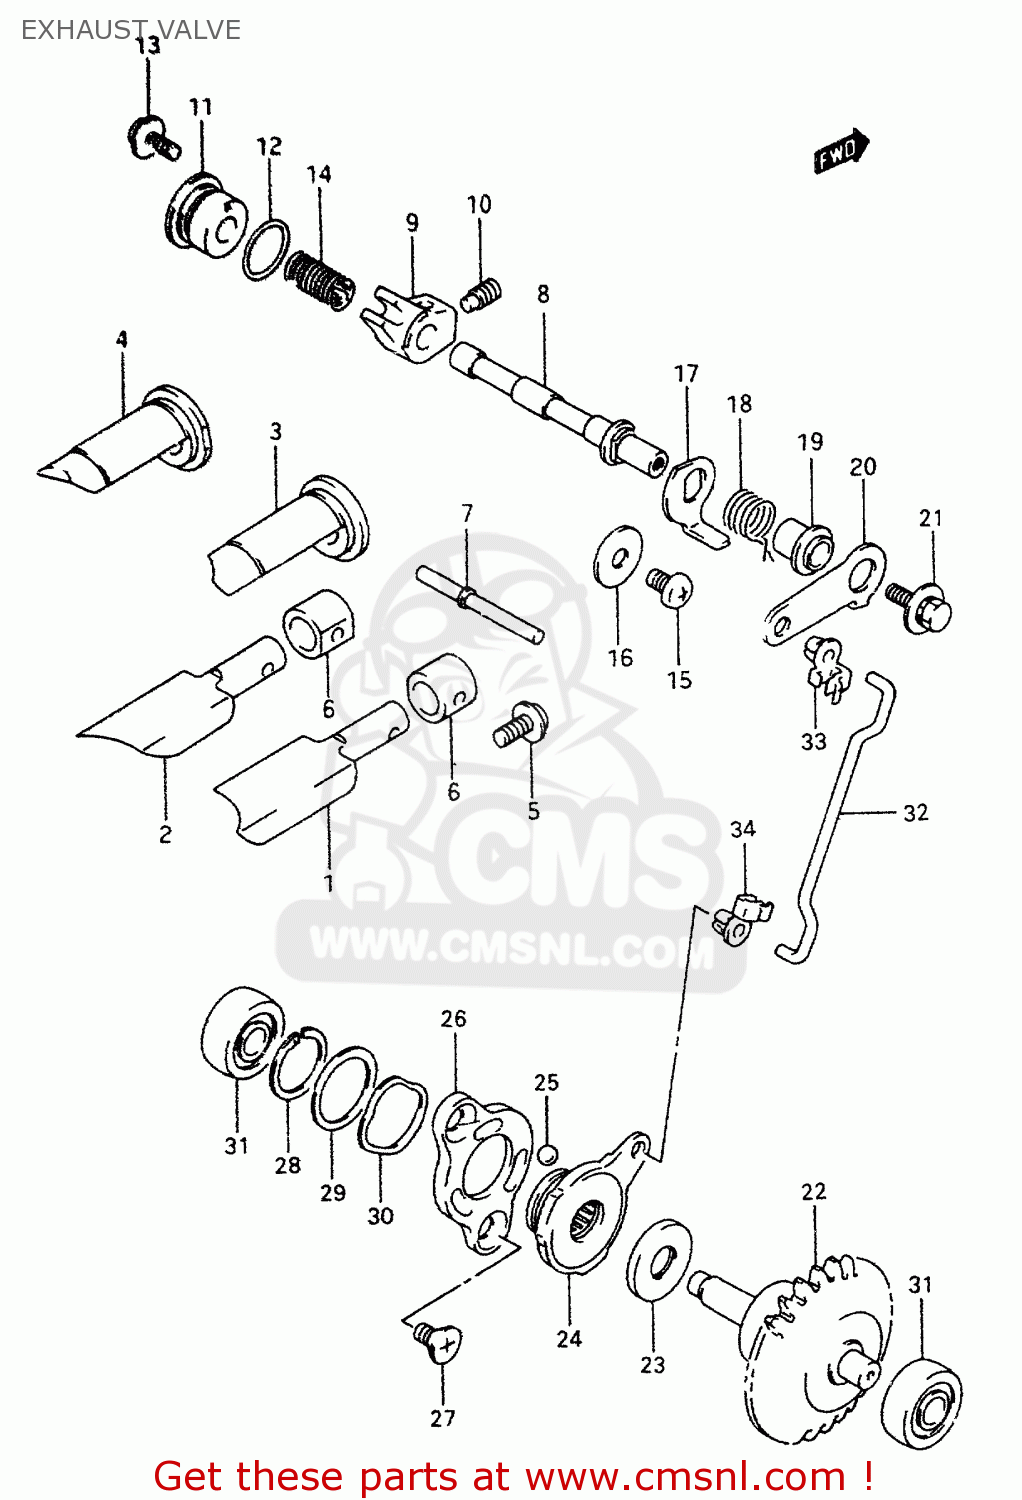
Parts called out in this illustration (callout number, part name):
1	VALVE,EXHAUST,R
2	VALVE,EXHAUST,L
3	GUIDE,EXHAUST VALVE,R
4	GUIDE,EXHAUST VALVE,L
5	SCREW 5X12
6	SPACER,EXHAUST VALVE
7	PIN,EXHAUST VALVE 48.5MM
8	SHAFT,EXHAUST VALVE
9	ARM,EXHAUST VALVE SHAFT
10	SCREW(6X10)
11	CAP,EXHAUST VALVE
12	O RING(D:1.9,ID:14.5)
13	BOLT
14	SPRING
15	SCREW
16	WASHER
17	LEVER,EXHAUST VALVE NO.2
18	SPRING
19	SPACER,EXHAUST VALVE
20	LEVER,EXHAUST VALVE NO.1
21	BOLT(5X12)
22	GOVERNOR ASSEMBLY,EXHAUST
23	BEARING(10X22X2.8)
24	ACTUATOR,EXHAUST VALVE
25	BALL
26	STARTER,EXHAUST VALVE ACTUATOR
27	SCREW(5X10)
28	CIRCLIP
29	SHIM(19.1X25X0.3)
30	WASHER
31	BEARING(8X22X7)
32	ROD,EXHAUST VALVE
33	BUSH,EXHAUST VALVE ROD NO.1
34	BUSH,EXHAUST VALVE ROD NO.2
